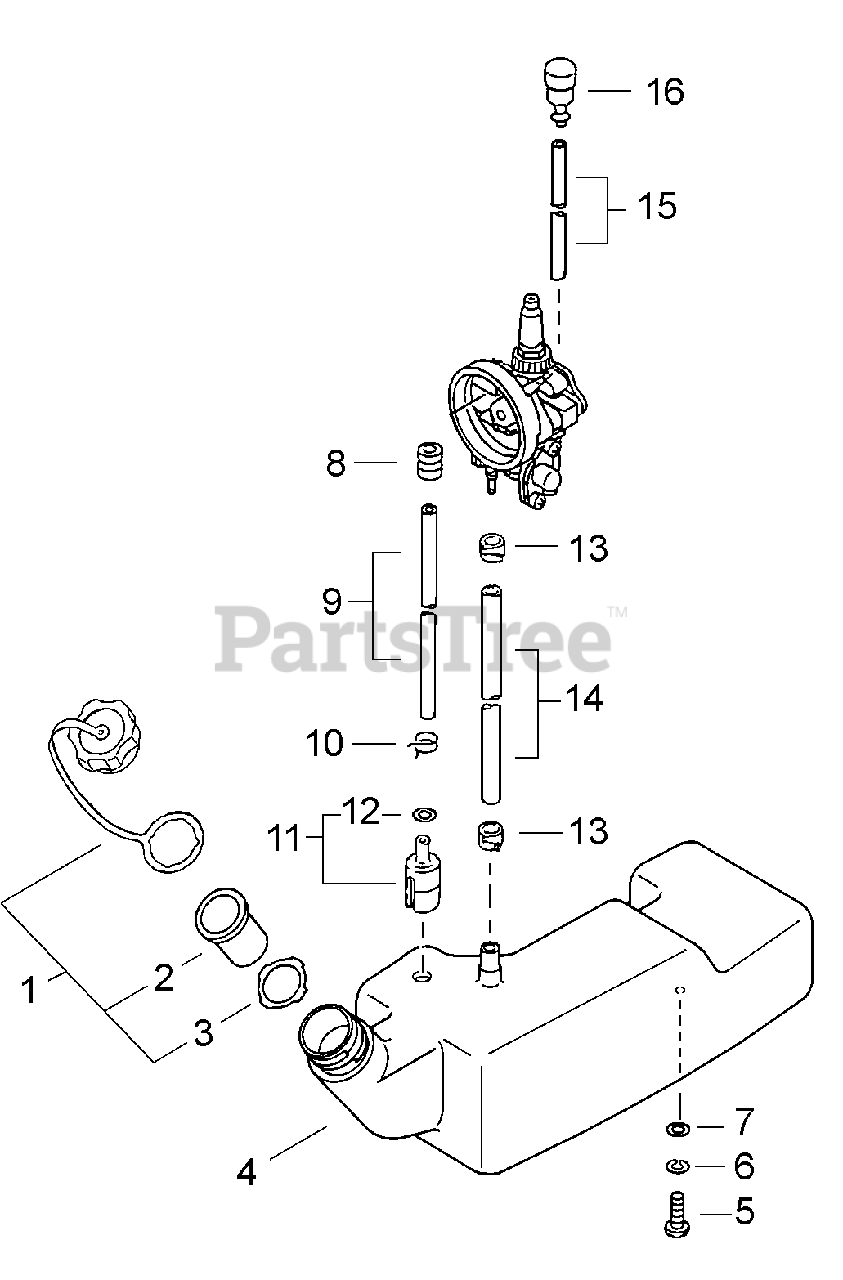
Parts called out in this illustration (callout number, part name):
1	CAP ASSY
2	VENT, CAP
3	GASKET, CAP
4	TANK, FUEL
5	SCREW - 6X14
6	LOCKWASHER - 6
7	WASHER - 6.5
9	PIPE - 3X6X230 -- BLACK
10	CLIP - 6.5
11	FILTER, FUEL
12	WASHER - 5
14	PIPE - 5/16 X 7/16 X 75
15	PIPE - 3X6X85 -- BLACK
16	VENT, FUEL TANK
